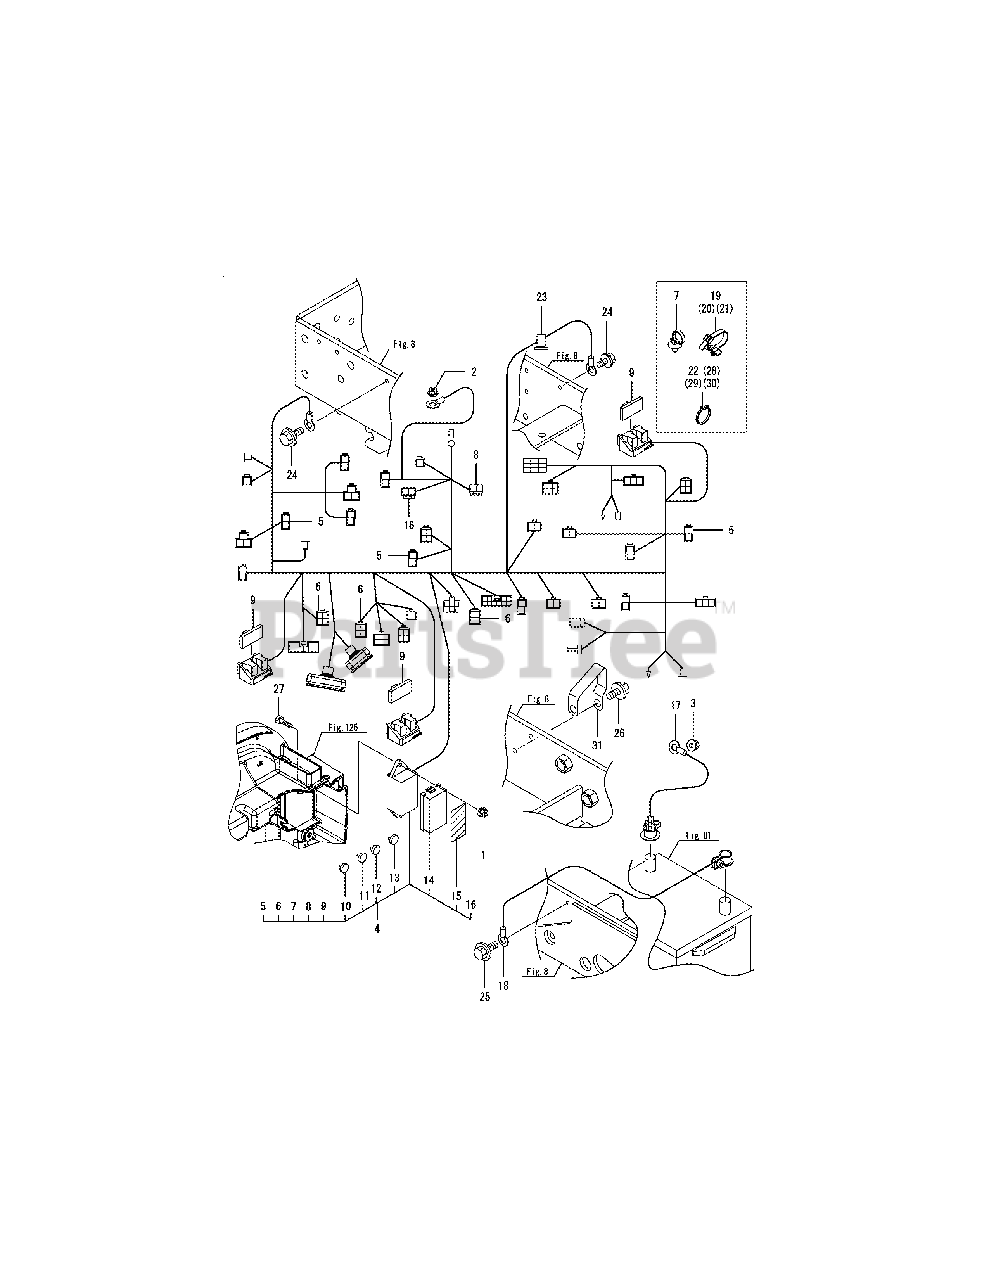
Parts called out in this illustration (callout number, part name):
1	NUT W/WASHER 6
2	NUT W/WASHER 6
3	NUT W/WASHER 8
4	HARNESS ASSY, WIRE
8	BLOW, SLOW FUSE 60A
14	COVER, FUSE BOX
16	BLOW 79A,SLOW CMP
17	CABLE, BATTERY
18	CABLE, BATTERY NEG.
23	STICKER 18,WIRE
24	BOLT M 8X 16 PLATED
25	BOLT M 8X 16 PLATED
26	BOLT M10X 20 PLATED
